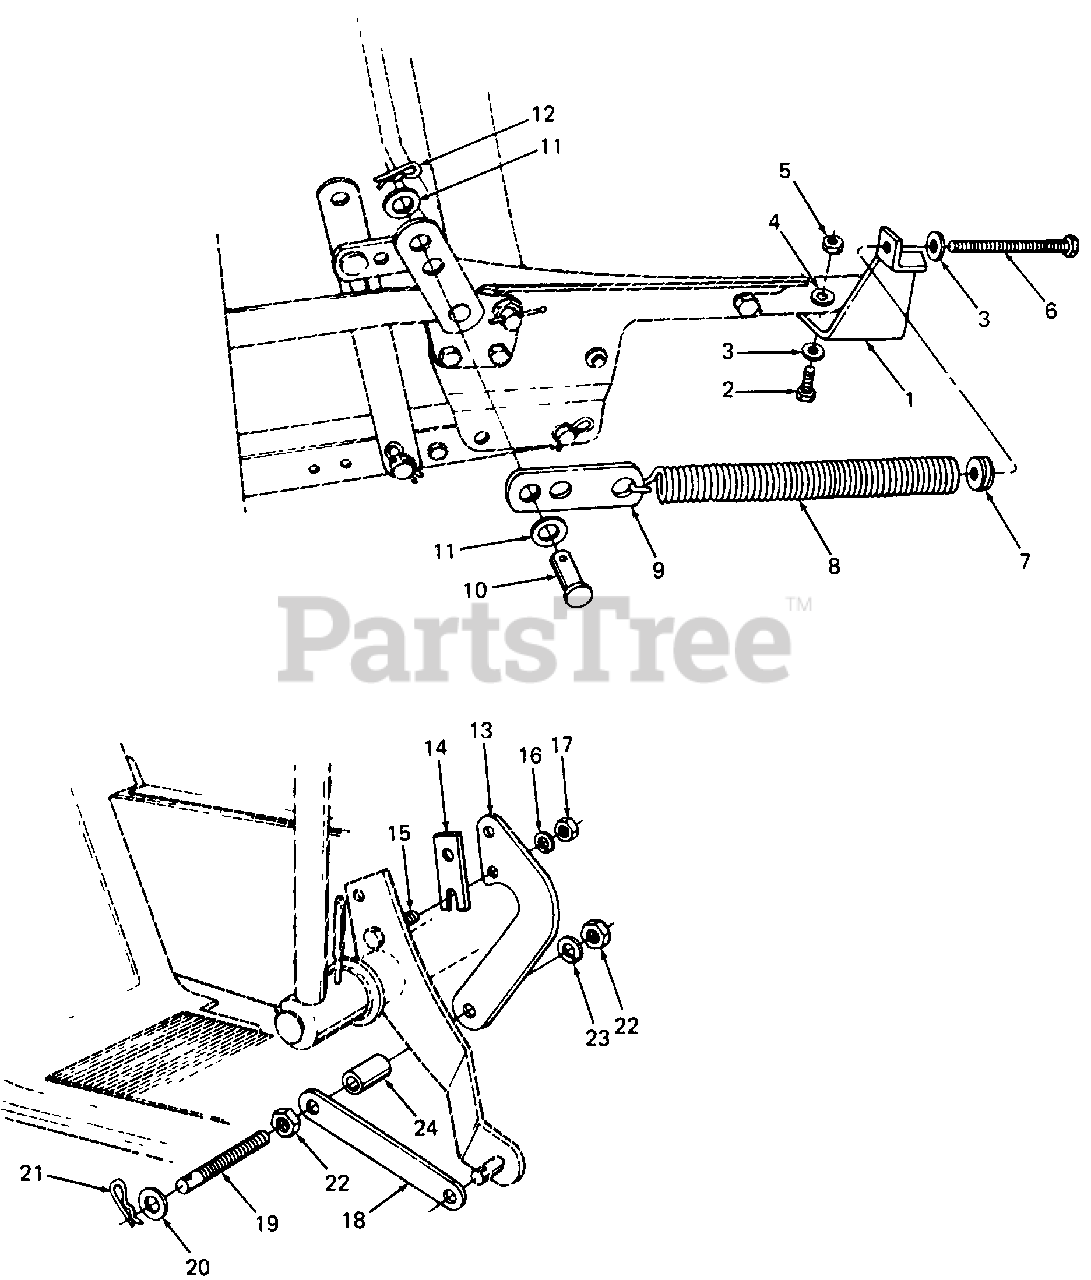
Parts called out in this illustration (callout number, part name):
1	Bracket, Helper Spring
2	Screw, Hex Cap, 3/8-16 X 1.0 Lg
3	Washer, Bell
4	Washer, Flat, .406 X 1.25 X .172 Thk
5	Nut, Hex, 3/8-16
6	Screw, Hex Cap, Special
7	Insert, Spring
8	Spring, Extension
11	Washer, Flat, .635 X 1.00 X .067 Thk
12	Pin, Internal Cotter
15	Screw, Hex Cap, 3/8-24 X 1.25 Lg GR5
16	Washer, Lock, 3/8
17	Nut, Hex, 3/8-24
18	Link, Lift
19	Pin, Lift Handle
20	Washer, Flat, .51 X 1.00 X .060 Thk
21	Pin, Internal Cotter
22	Nut, Hex Jam, 1/2-20
23	Washer, Lock, 1/2
24	Spacer, .55 X .75 X 1.00 Lg
